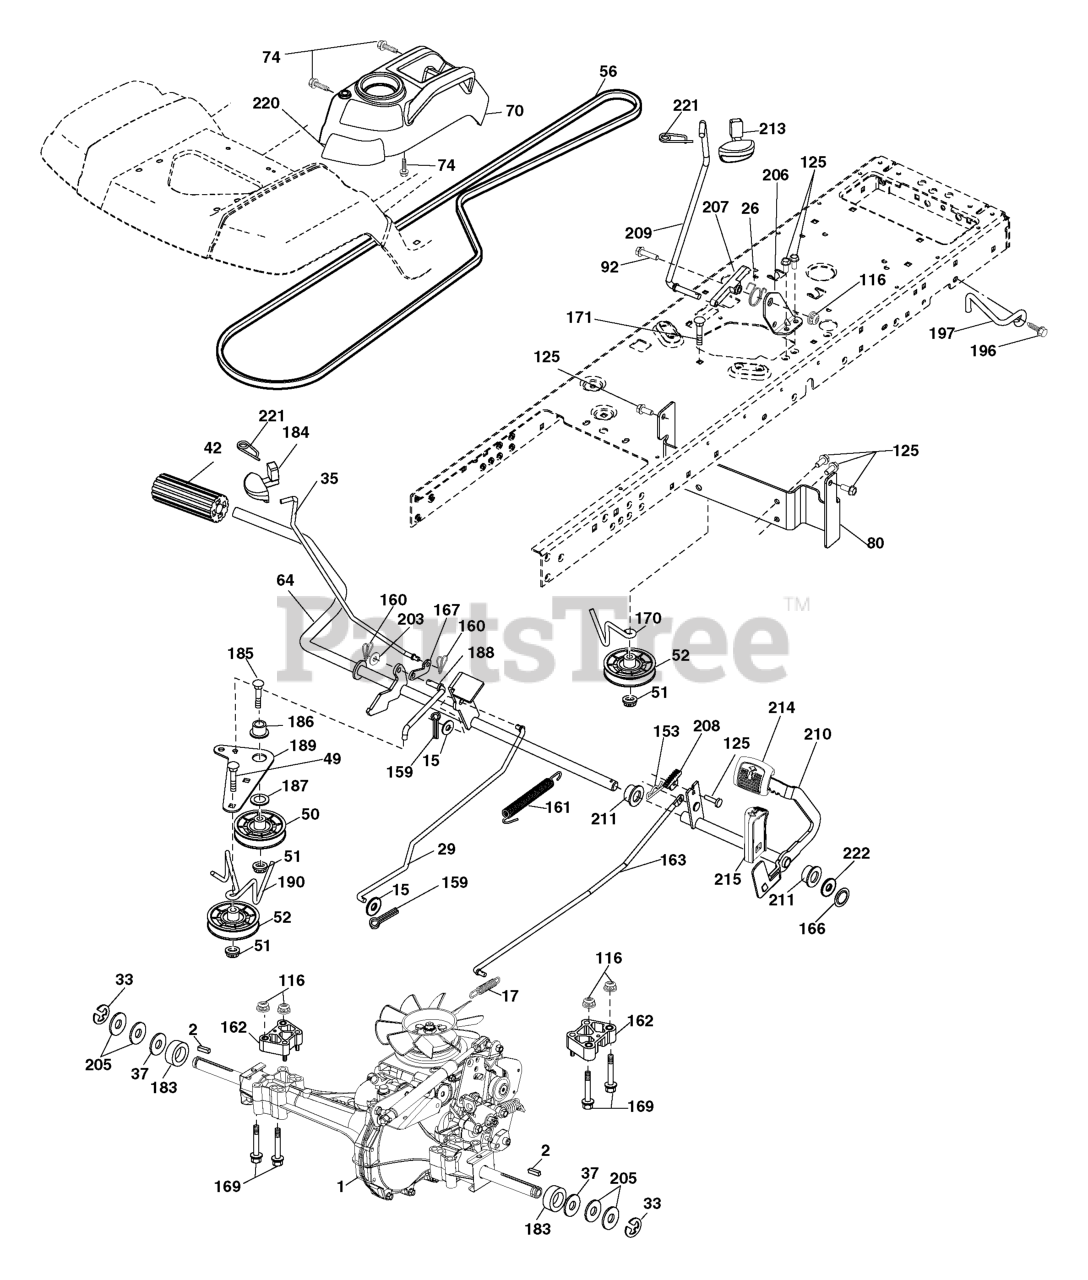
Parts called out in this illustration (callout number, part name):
2	SQUARE KEY
15	WASHER
17	SPRING.BRAKE.HG3000/3500
26	SPRING.RETURN.CRUISE
29	ROD.BRAKE.0610.PEDAL.CONTROL
35	ROD.BRAKE.PARKING.GT.H
42	PEDAL COVER T
50	IDLER.FLAT.910.OFFSET
51	NUT LOCK FLG 3/8-16 UNC
52	IDLER.V-GROOVE.910.OFFSET
64	SHAFT.ASM.PEDAL.BRK.CNTR
70	RP CONSOLE.ASM.PCH.W/TB
74	SCREW.HI-LO.CONSOLE
80	BRKT.STRP.TRQ.LT.HYD.C
92	BOLT
116	NUT LOCK HEX FLANGE 5/16-18
125	SCREW
153	RETAINER M
159	COTTER PIN
160	RETAINER CLIP
161	SPRING.RETURN.CLUTCH.2006
162	SPACER.TRANSAXLE.18&22
163	ROD.PEDAL.CONTROL.0510
166	NUT.PUSH.625.2006
167	LATCH.BRAKE.SPRING
169	BOLT.HEX.FLNG.5/16-18X3.75
170	KEEPER.V-IDLER.CENTER.
171	BOLT
183	SPACER AXLE
184	HANDLE.PARKG.BRK.HUSQ X667
185	BOLT
186	SPACER.RETAINER
187	WASHER 12/32X2X10GA
188	RP.LINK.CLUTCH.GROUND.DRIVE
189	BELLCRANK.GROUND.DRIVE.TEX.
190	KEEPER.BELLCRANK.DRIVE
196	SCREW 3/8-16X1
197	LINK.CLUTCH.ANIT-ROTAT
203	WASHER
206	BRKT.MOUNT.LATCH.CRUIS
207	LATCH.CONTROL.CRUISE
208	GEAR.SECTOR.CONTROL.CR
209	ROD.CONTROL.CRUISE.GT.
210	ROCKER.ASM.PEDAL.CONTR
211	BEARING.NYLON
213	KNOB.CONTROL.CRUSIE.HU
214	PEDAL.FORWARD.TEX.GT.4
215	PEDAL.REVERSE.TEX.GT.4
220	REFLECTOR.RH.TEX GT
221	RETAINER.SPRING.CLIP.H
222	WASHER
